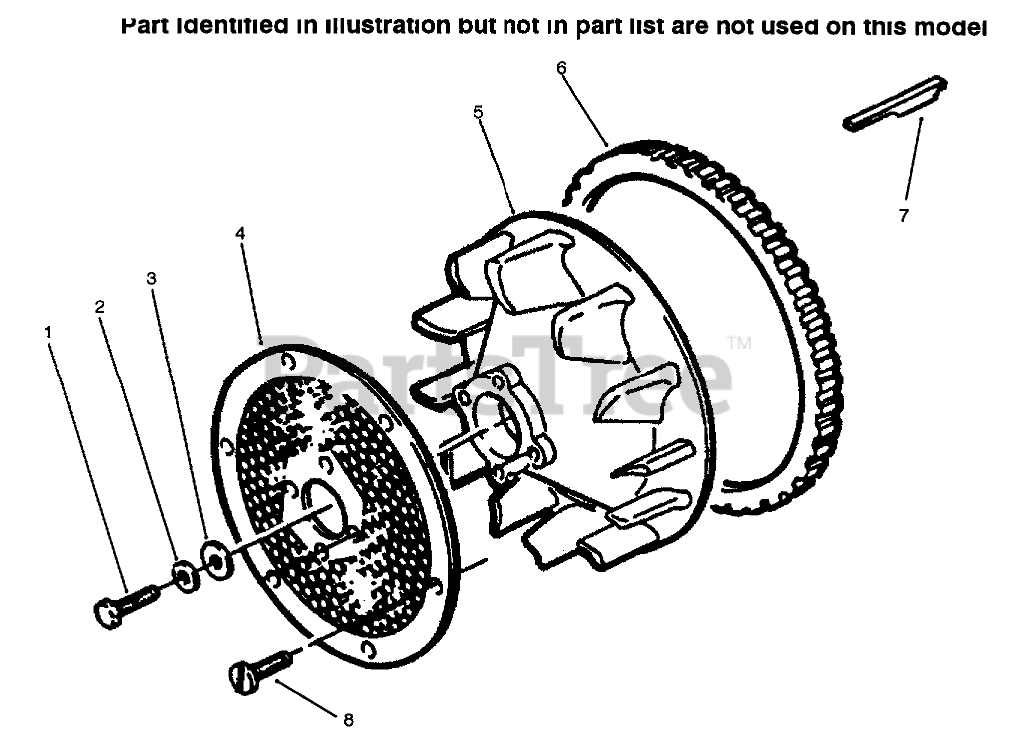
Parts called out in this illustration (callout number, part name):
1	SCREW
2	WASHER-FLAT
3	WASHER-FLAT
4	Screen
5	WHEEL BLOWER
7	KEY-FLYWHEEL
8	LOCK SCREW
